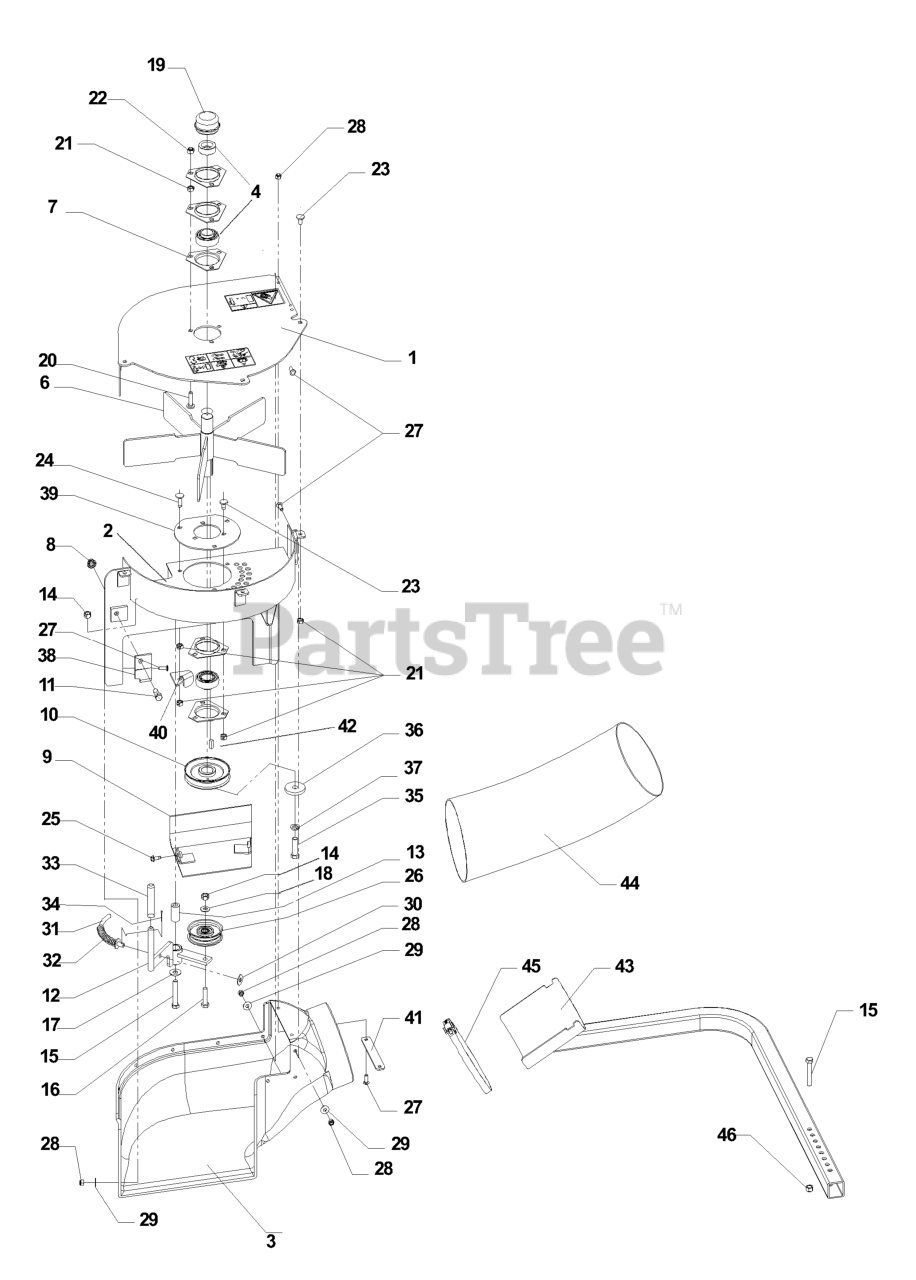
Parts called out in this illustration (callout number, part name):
1	FAN COVER W/DECALS
2	UPPER HOUSING
3	LOWER HOUSING
4	BEARING KIT-2 PCS
6	FAN
7	BRG FLANGE
8	NUT 3/8C WHIZ
9	SHEAVE FLOOR WELDMENT
11	HCS 3/8-16X1.GRD.5.ZD
13	BUSHING, SLEEVE
14	NUT 3/8C CENTERBLOCK
15	HCS 3/8C X 2 1/4
16	HCS 3/8C X 1 1/2
17	WASHER 3/8 FLAT
18	WASHER 3/8 SAE FLAT
19	GREASE CAP
20	BOLT, CARRIAGE 5/16X1-1/4
21	NUT 5/16C CENTERLOCK
22	NUT 5/16 NYLOC
23	CARRIAGE BOLT 5/16C X 5/8"
24	RHSNB 5/16C X 1
25	SCREW 1/4 X 5/8
27	RHSNB 1/4C X 3/4
28	NUT.1/4-20.HEX.NYLOC.ZD
29	WASHER 1/4 FLAT
30	FLAT WASHER 5/16 SAE
31	SPRING ROD WLDMNT
34	COTTER PIN 3/32 X 3/4
35	HCS 7/16F X 1 1/2
36	SPINDLE WASHER
37	WASHER 7/16 LOCK
39	BEARING PLATE - BLACK
40	BELT GUIDE
41	BACKING (BLACK)
42	KEY 1/4 SQ X 3/4
43	SUPPORT WELDMENT
44	HOSE 7 X 82 CLEAR
45	HOSE CLAMP 4-1/8 TO 7"
46	NUT 3/8-16 NYLOC
